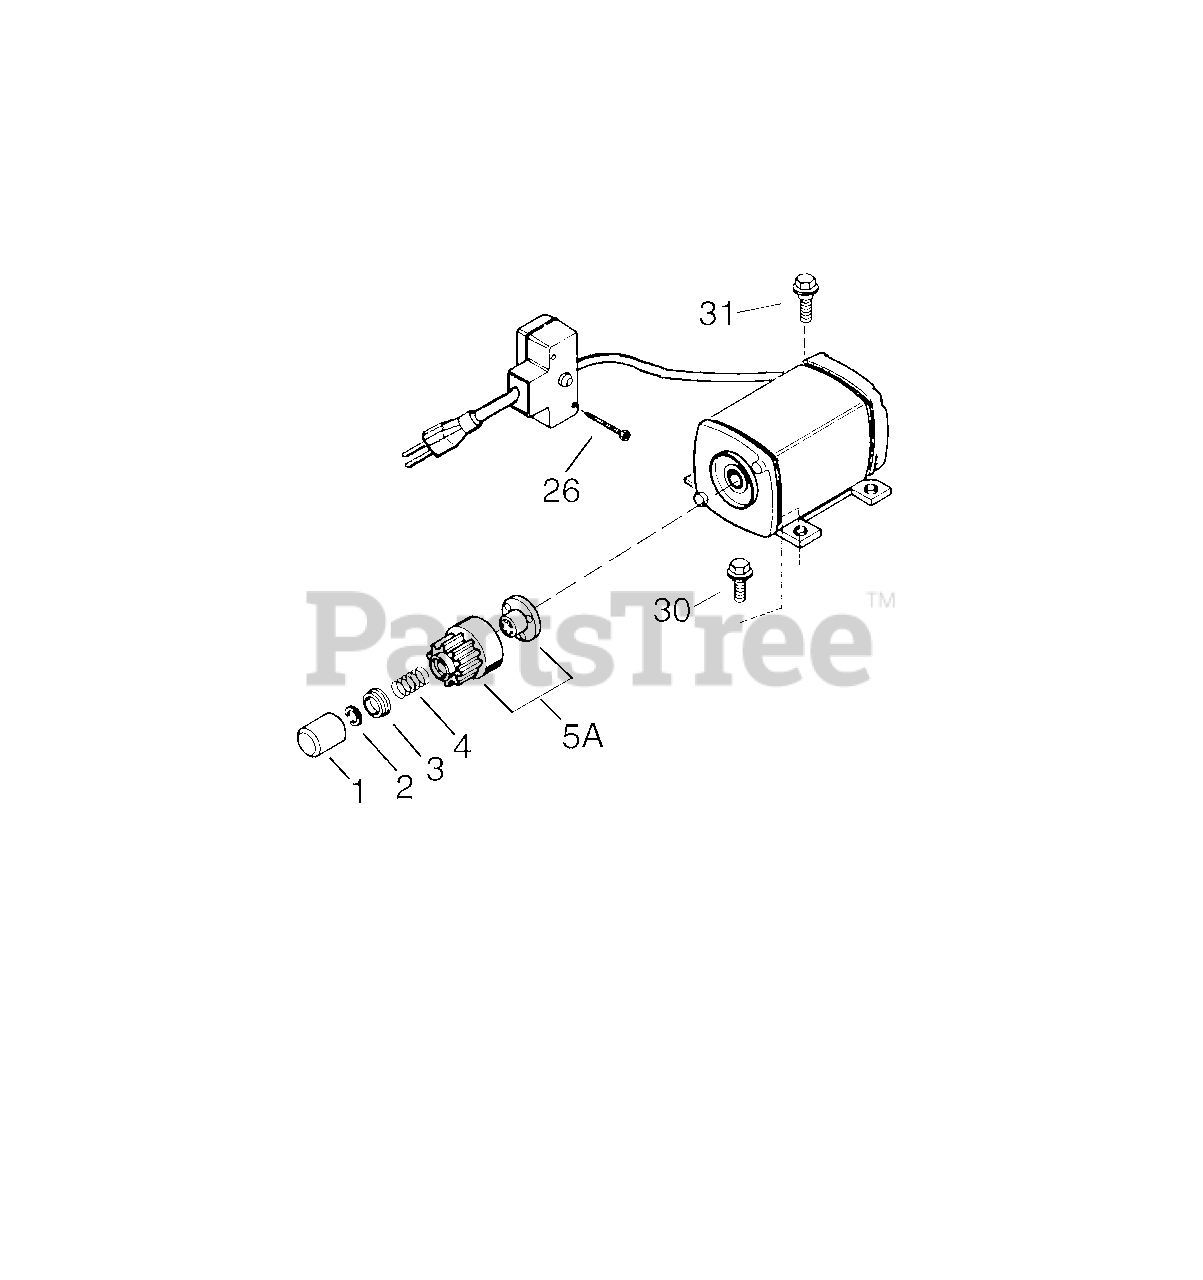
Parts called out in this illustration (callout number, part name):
1	Dust Cover
2	Retainer Ring
3	Spring Retainer
4	Anti-drift Spring
5A	Gear & Nut (Incl. 2)
26	Screw, 6-32 X 2-1/2"
26	Screw, 12-16 x 5/8"
30	Screw, T-30, 1/4-20 x 1/2"
31	Screw, 1/4-20 X 1/2" (NOTE: Interna l parts are no t serviceable. In the event of electrical failure, the enti re motor must be replaced.)
